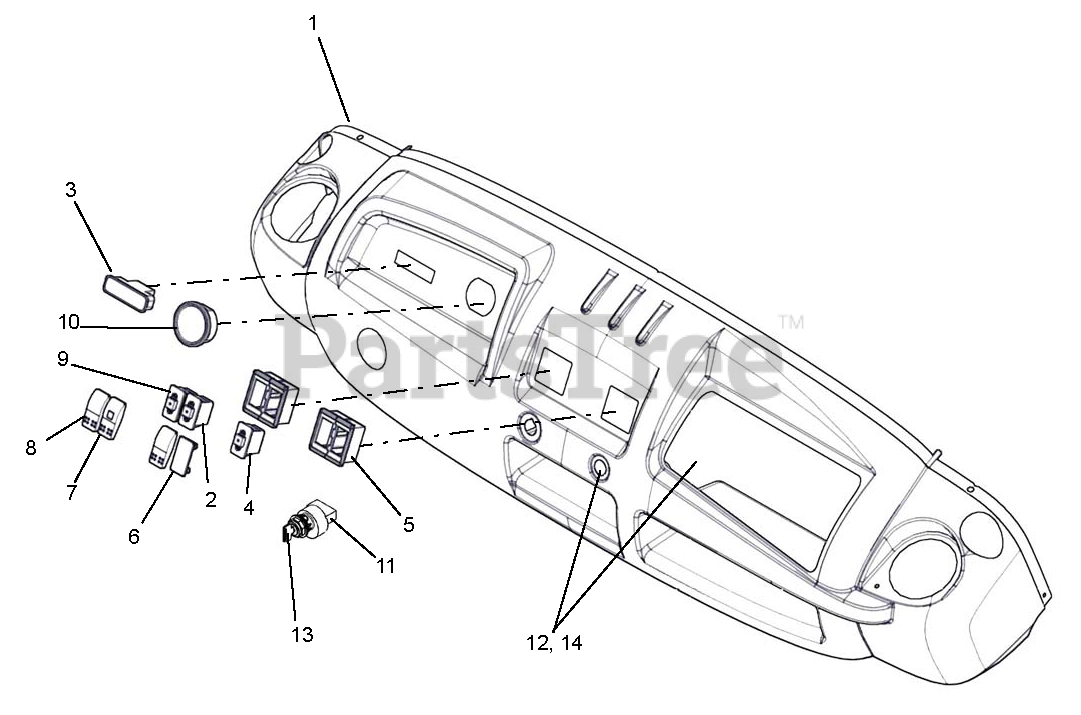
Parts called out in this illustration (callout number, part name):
1	ASSEMBLY,DASH/GLOVEBOX
2	SWITCH,4X4,LIGHTED
3	INDICATOR LAMP, 6 LENS
4	DUMP SWITCH WAYTEK 44304
5	SWITCH MOUNT END
6	PANEL PLUG
7	ACTUATOR,SWITCH,4X4
8	SWITCH ACTUATOR
9	SWITCH,HEADLIGHT
10	GAUGE, FUEL/HOUR METER
11	IGNITION SWITCH W/2 KEYS(6PIN)
12	POWER OUTLET, 12VOLT
13	KEY W/SHIELD
14	CAP, 12V OUTLET
